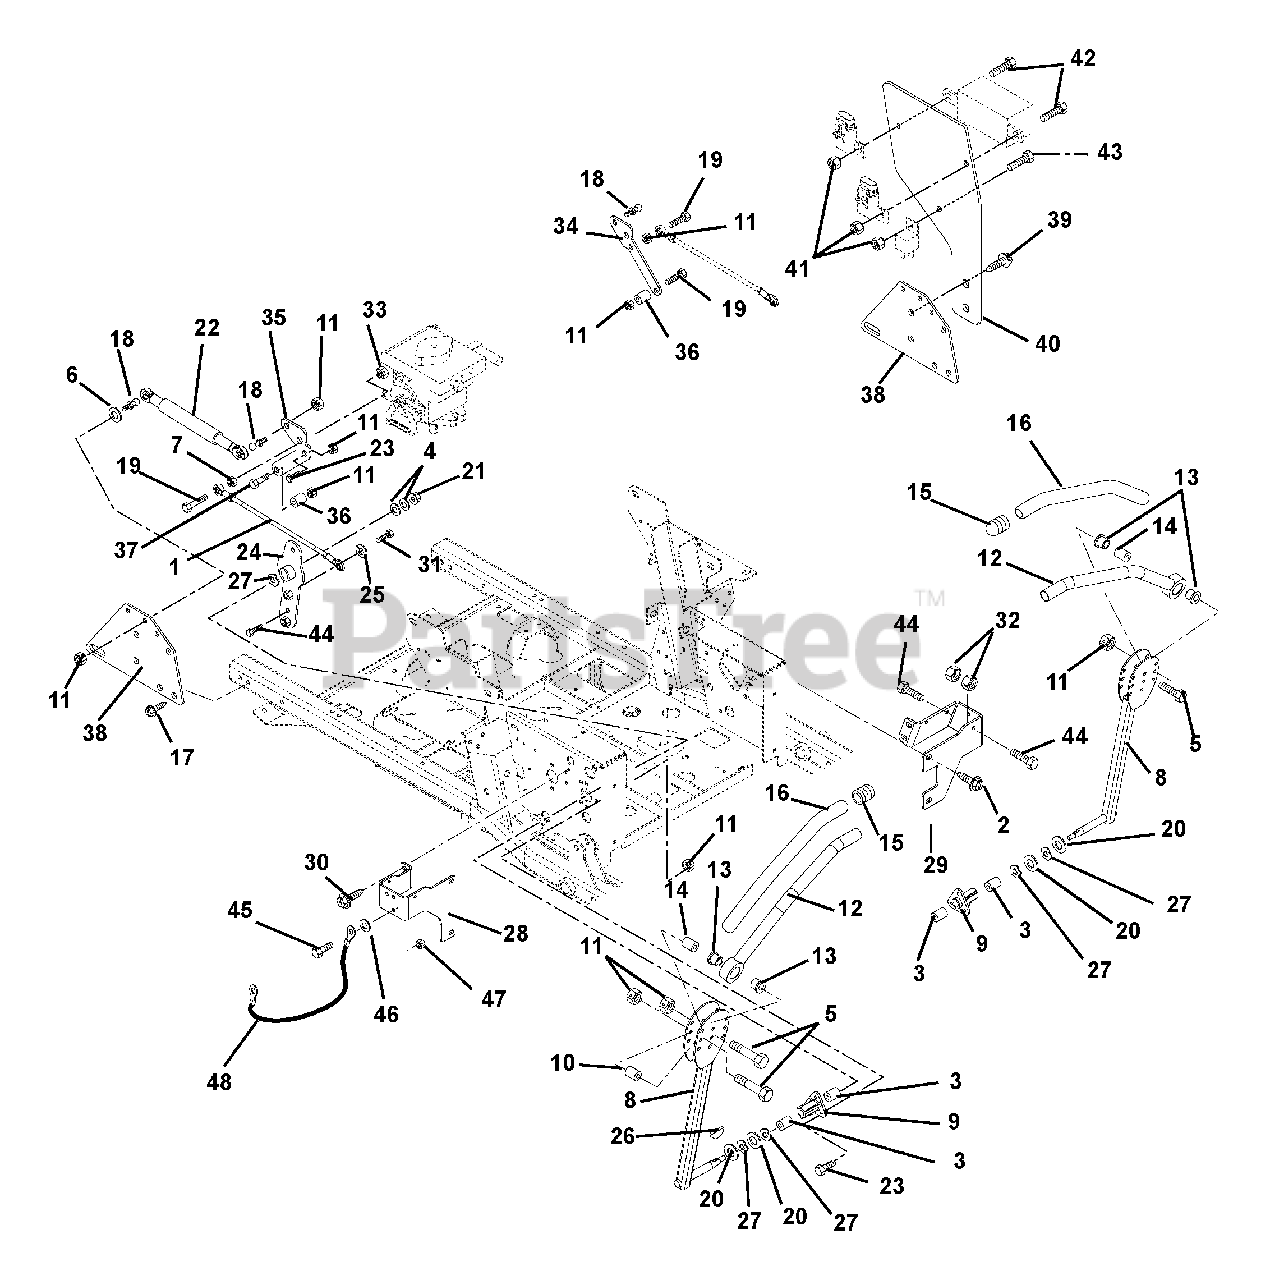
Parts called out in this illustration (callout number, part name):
1	Assembly, Steering Rod .38 Rod x 7.60
2	Screw, Tapping .38-16 x .75 Hex Washer Head
3	Bushing .625 x .75 x .50
4	Washer, Flat Steel .403 x .812 x .065
5	Bolt, Hex .31-18 x 1.75 Grade 5
6	Washer, Flat Steel .344 x .688 x .065
7	Nut, Hex .38-16
8	Control Arm
9	Bushing, Flange
10	Eccentric
11	Nut, Locking Top Flange .31-18
12	Handle Weldment Left-Hand
12	Handle Weldment Right-Hand
13	Bushing, Flange Nylon .762 x 1.48 x .44
15	Caplug, Handlebar
16	Grip, Handlebar
17	Screw, Tapping .31-18 x .50 Hex Washer Head
18	Stud, Ball
19	Bolt, Hex .38-16 x 1.50 Grade 5
20	Washer, Flat Steel .63 x 1.005 x .062
21	Nut, Locking Top Flange .38-16
22	Damper, Control
23	Bolt, Hex .31-18 x .75 Grade 5
24	Weldment, Pivot Arm
25	Washer, Locking .38 x .094 Regular
26	Key, Woodruff .13 x .63
27	Washer, Wave
28	Stop, Steering Right Hand
29	Stop, Steering Left Hand
30	Screw, Tapping .38-16 x .50 Hex Washer Head
31	Bolt, Hex .38-16 x 1.25 Grade 5
32	Nut, Hex Jam .375-16
33	Nut, Locking Center .38-16
34	Bracket, Left Hand
35	Bracket, Right Hand
36	Spacer .318 x .43 x .375
37	Bolt, Hex .31-18 x 1.25 Grade 5
38	Bracket, Damper
39	Screw, Tapping .38-16 x .50 Hex Washer Head (091, 107)
40	Bracket, EFI Box Mount (091, 107)
41	Nut, Locking Nylon 10-24 with Insert (091, 107)
42	Screw, Machine 10-24 x 2.00 Hex Washer Head (091, 107)
43	Screw, Machine 10-24 x .50 Hex Washer Head (091, 107)
44	Bolt-Hex .375-16 x 1.75 Full Thread
45	Bolt-Hex .25-20 x .75 Grade 5
46	Washer, Flat Steel .265 x .50 x .087
47	Nut, Locking Top Flange .25-20
48	Cable, Hood
